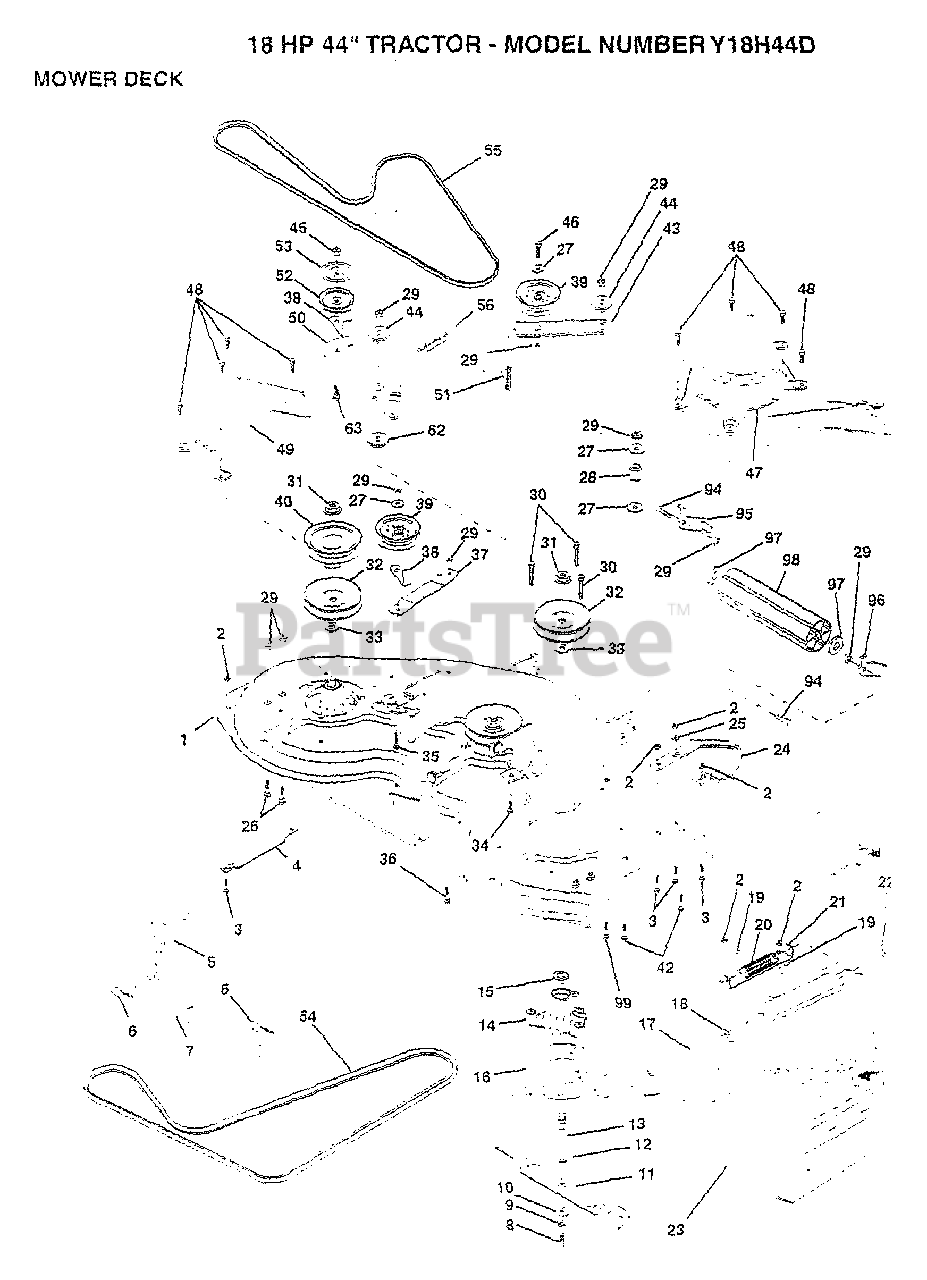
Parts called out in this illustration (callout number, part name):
1	"DECK ASM WELD44"""
2	NUT
4	RUNNER-LH M
5	BRKT.ASM.SW.44/50
8	BLADE BOLT
10	WASHER.HARD.BLADE
11	"BLADE.44"" HIPERF"
12	BEARING.BALL
13	SHAFT.ASM.W/BRNG
14	HOUSING.MAND.44.V
15	BEARING
16	STRIPPER RND MWR
17	ROD-HINGE T
18	WASHER
19	CAP-SLEEVE LT
20	SPRING TORSION
21	BRKT DEFLECTOR
22	NUT PUSH M
23	DEFLECTOR SHIELD
24	RUNNER.RH
25	WASHER M
26	BOLT
27	WASHER
29	NUT
33	WASHER
34	BOLT.3/8-14X1.25
35	BOLT
36	BOLT D
37	STIFFENER.ARM.IDL
39	FLAT IDLER PULLEY
40	"PULLEY.DRIVEN.44"""
42	BOLT
43	"ARM.IDLER.SEC.44"""
44	SPACER RETAINER
47	"COVER.MAND.RH.44"""
48	SCREW.1/4-20X5/8
49	COVER.MANDREL.LH
50	ARM.IDLER.PRIMARY
51	"SPRING.SEC.44""VEN"
52	PULLEY.IDLER.VGRO
53	SHIELD.IDLER.44.V
54	V-BELT.PRIM.78.5.
55	BELT-V.88.12.MW
56	SPRING.EXT.DECK.
62	HARDENED WASHER
63	BOLT.3/8-16X1.50
94	BOLT
97	WASHER
99	BOLT
